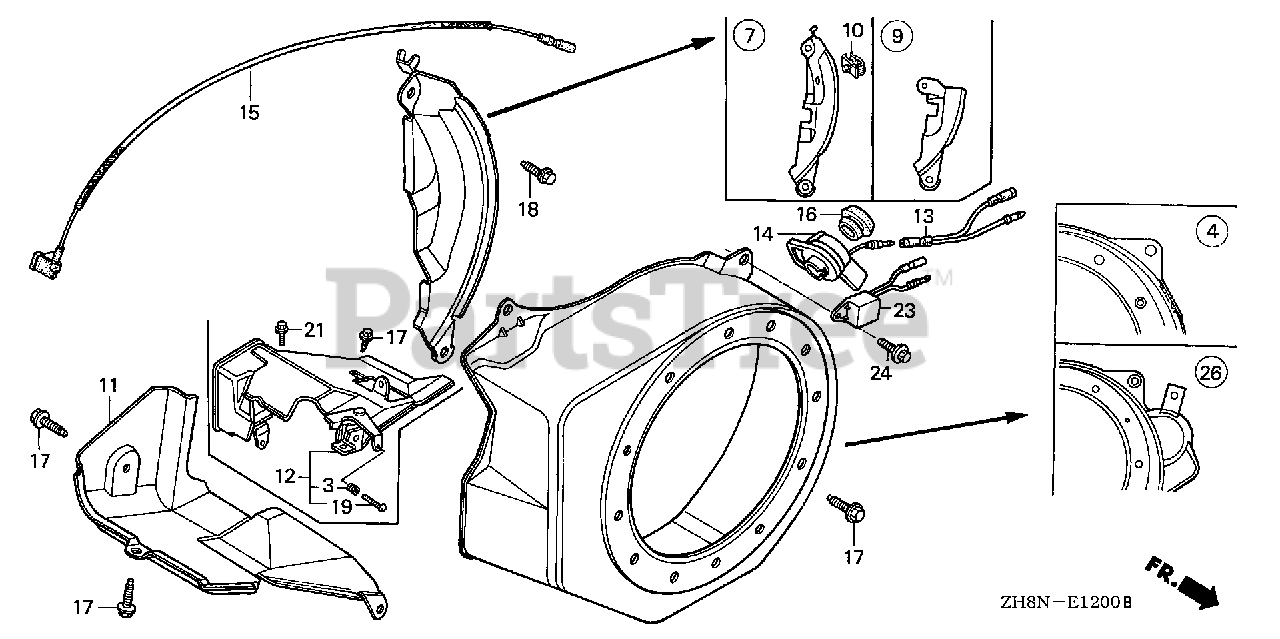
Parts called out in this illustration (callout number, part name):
4	COVER, FAN *R8* (BRIGHT RED)
7	PLATE, SIDE (OIL ALERT)
10	CLIP, HARNESS
11	SHROUD
14	SWITCH ASSY., ENGINE STOP
15	WIRE, STOP SWITCH (370MM)
17	BOLT, FLANGE (6X12) (CT200)
18	BOLT, FLANGE (6X20) (CT200)
